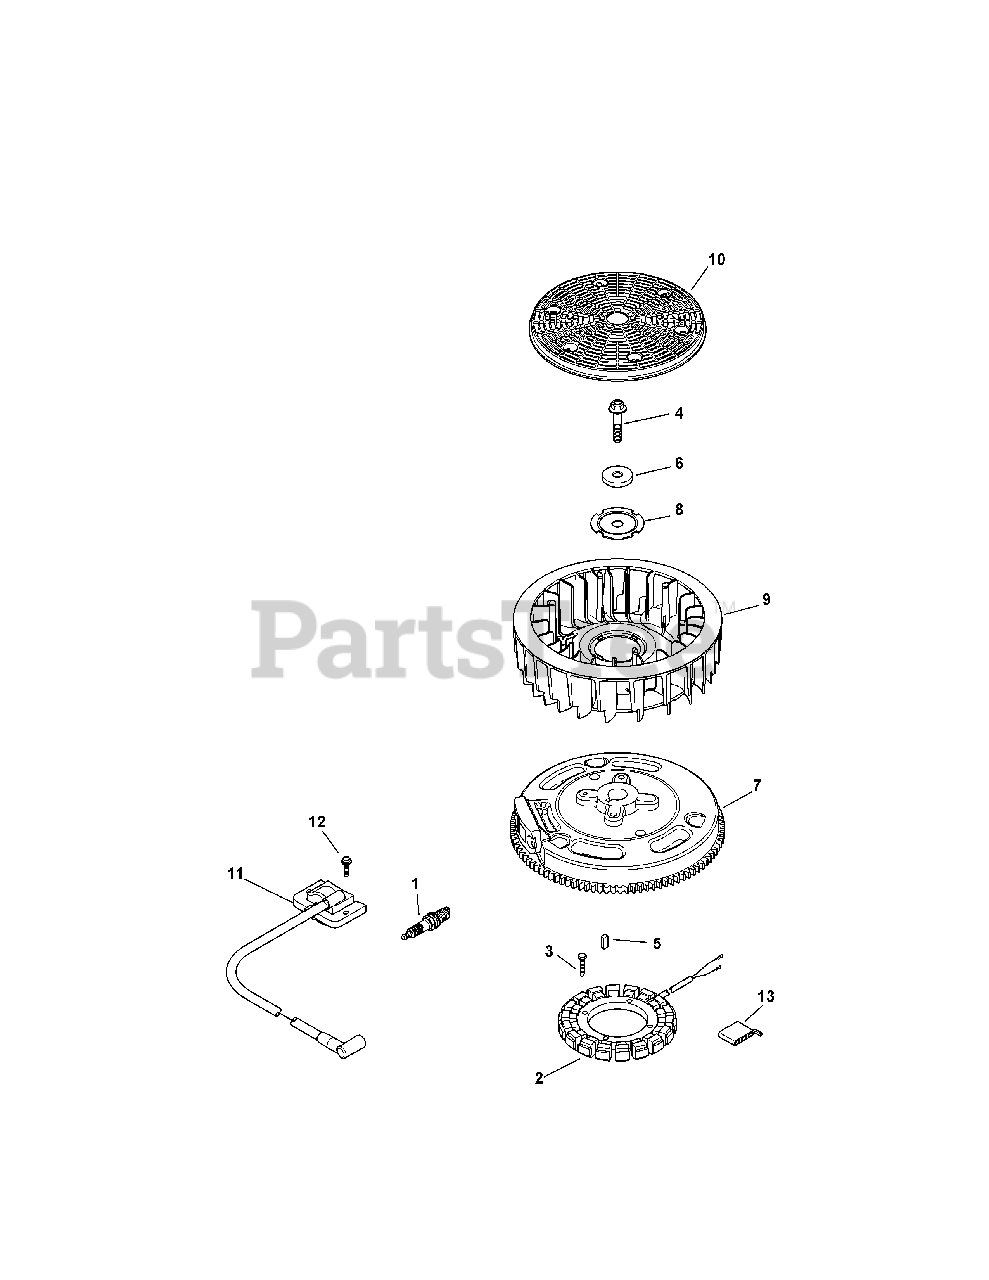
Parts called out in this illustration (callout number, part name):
1	Spark Plug
2	15 Amp Stator Kit
3	Screw, M5 x 0.8 x 25
4	Hex Flange Screw
7	Flywheel Assembly
8	Fan Mounting Plate
9	Fan
11	Module Ignition Kit
12	Screw, M5 x .8 x 20
